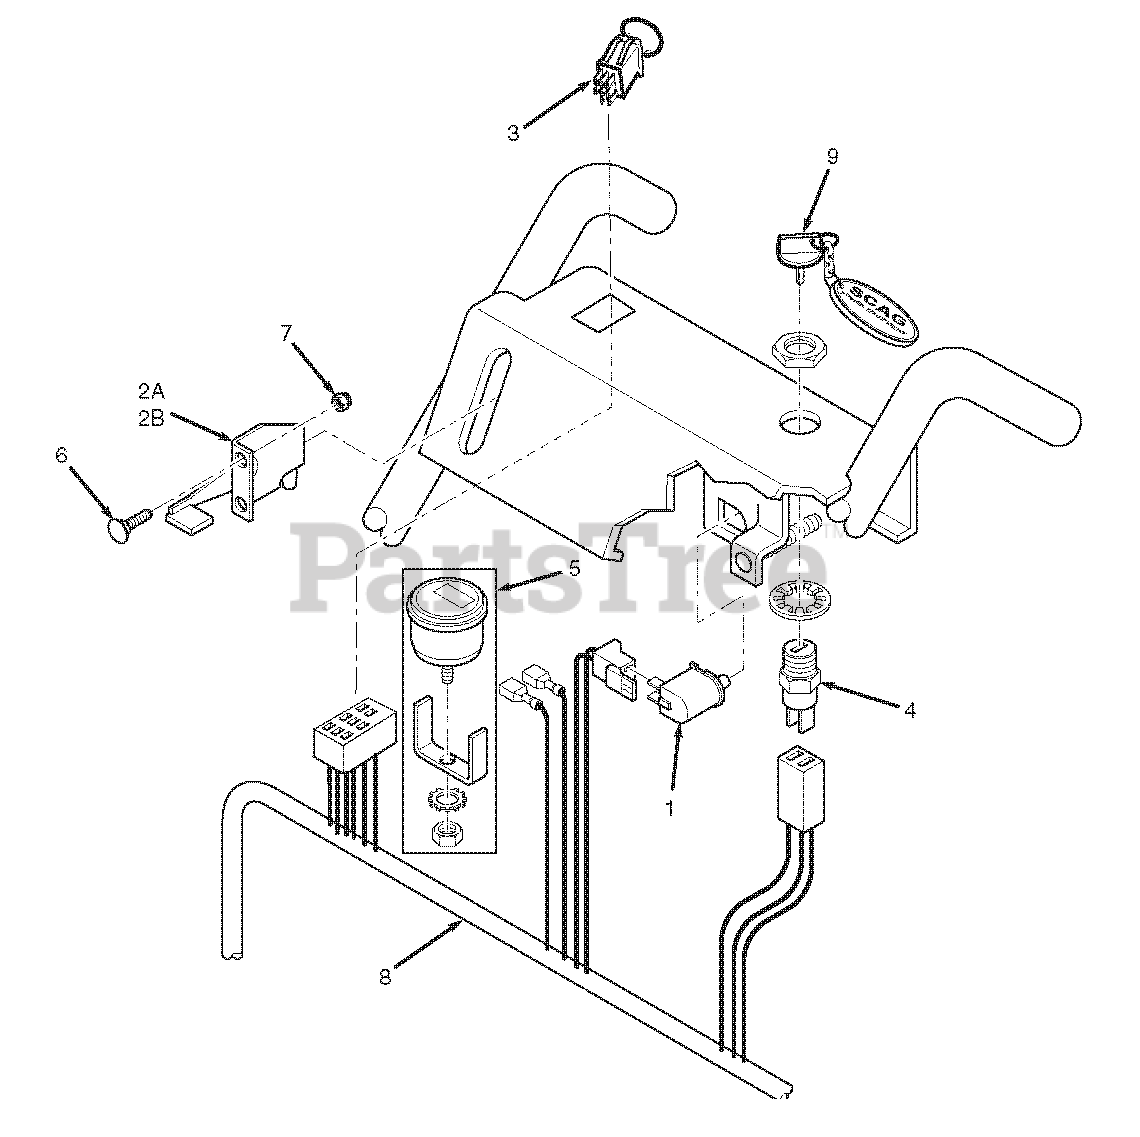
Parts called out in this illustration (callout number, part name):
1	Switch, Neutral Lock
2A	Throttle Contro - Kohler
2B	Throttle Control - Kawasaki
3	Engagement Switch, Electric Clutch
4	Key Switch
5	Hour Meter (dealer installed)
6	Bolt, Carriage #10-32 x 1/2"
7	Nut, #10-32 Elastic Stop
8	Handle Wire Harness, Manual Start
9	Key Chain w/Keys
9	Key w/Shroud
